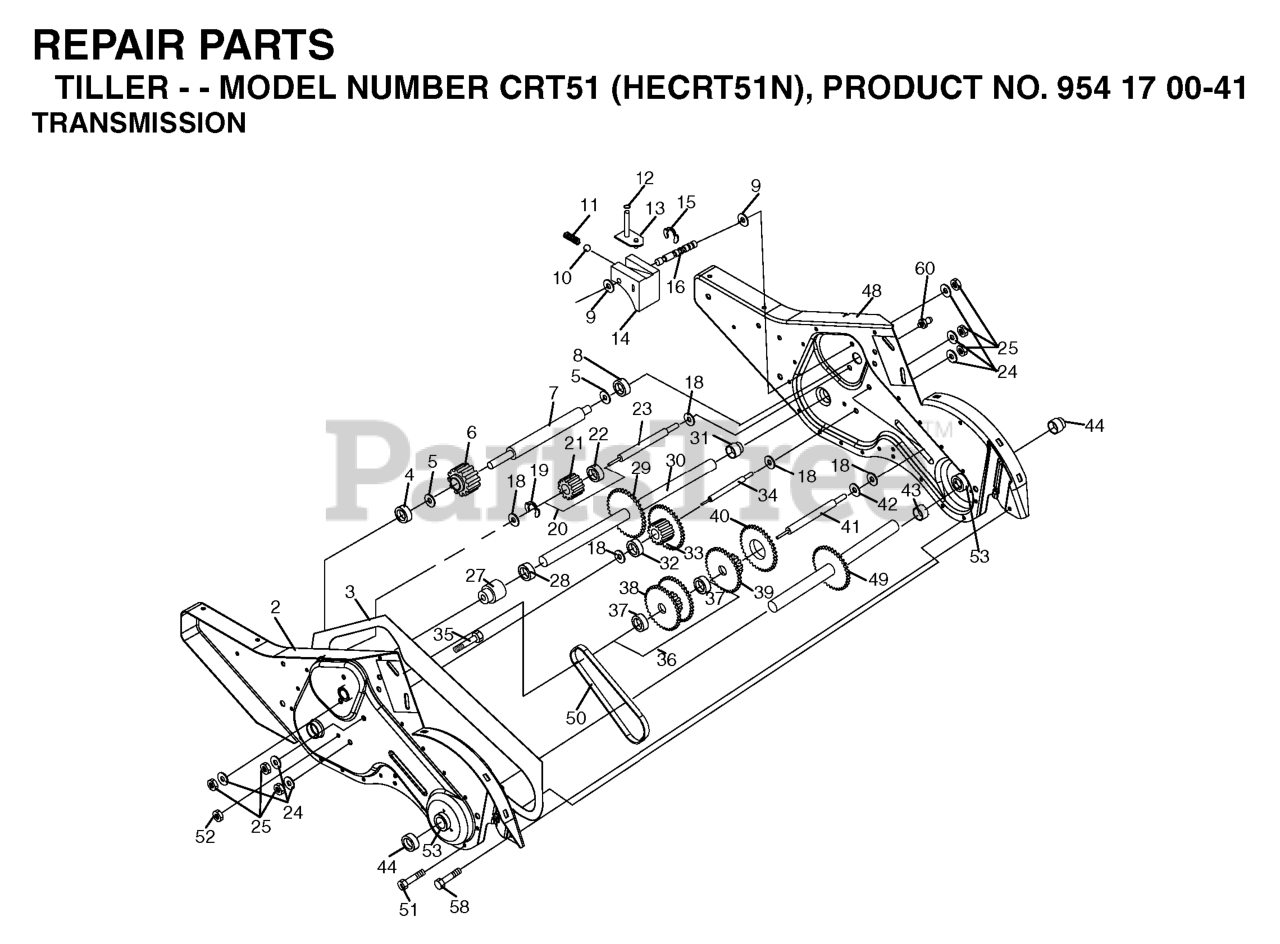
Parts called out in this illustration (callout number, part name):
1	TRANSMISSION ASM.
2	GEARCASE.ASM.CRT.LH.W/BEARING
3	GASKET
4	NEEDLE BRNG LT
5	THRUST WASHER
6	GEAR.PINION.INPUT
7	SHAFT.INPUT."D".TILLER
8	BEARING TI
9	WASHER, SEAL (2 2)
10	STEEL BALL KIT
11	SPRING-SHIFT CRT
13	BRACKET ASM.SHIFT.CRT
14	SHIFT FORK TI
16	SHAFT.SHIFTER.TILLER
20	GEAR ASSY CRT
21	GEAR-REV IDLR CRT
22	NEEDLE BEARING TI
24	LOCKWASHER
25	NUT.ASF.HEX.7/16
27	BEARING, SHAFT LH CRT
30	GROUND SHAFT ASS'Y
31	BEARING, SHAFT RH CRT
33	SPRCKT 8 GEAR CRT
34	SHAFT.SECONDARY.REDUCTION.CRT
35	SCRW WHIZ LOK CRT
36	SPROCKET.ASM.W/BEARING.TILLER
37	BEARING
38	SPROCKET, TINE
41	SHAFT.REDUCTION.TILLER
42	BRNG RACE T
44	SEAL ASM, OIL
48	GEARCASE.ASM.CRT.RH.W/BEARING
49	TINE SHAFT
50	CHAIN.TILLER
51	SCREW
53	KIT.BEARING.TILLER.
58	BOLT SHOULDER 1/4-20 UNC X.875
60	FITTING.GREASE.TAPERED
